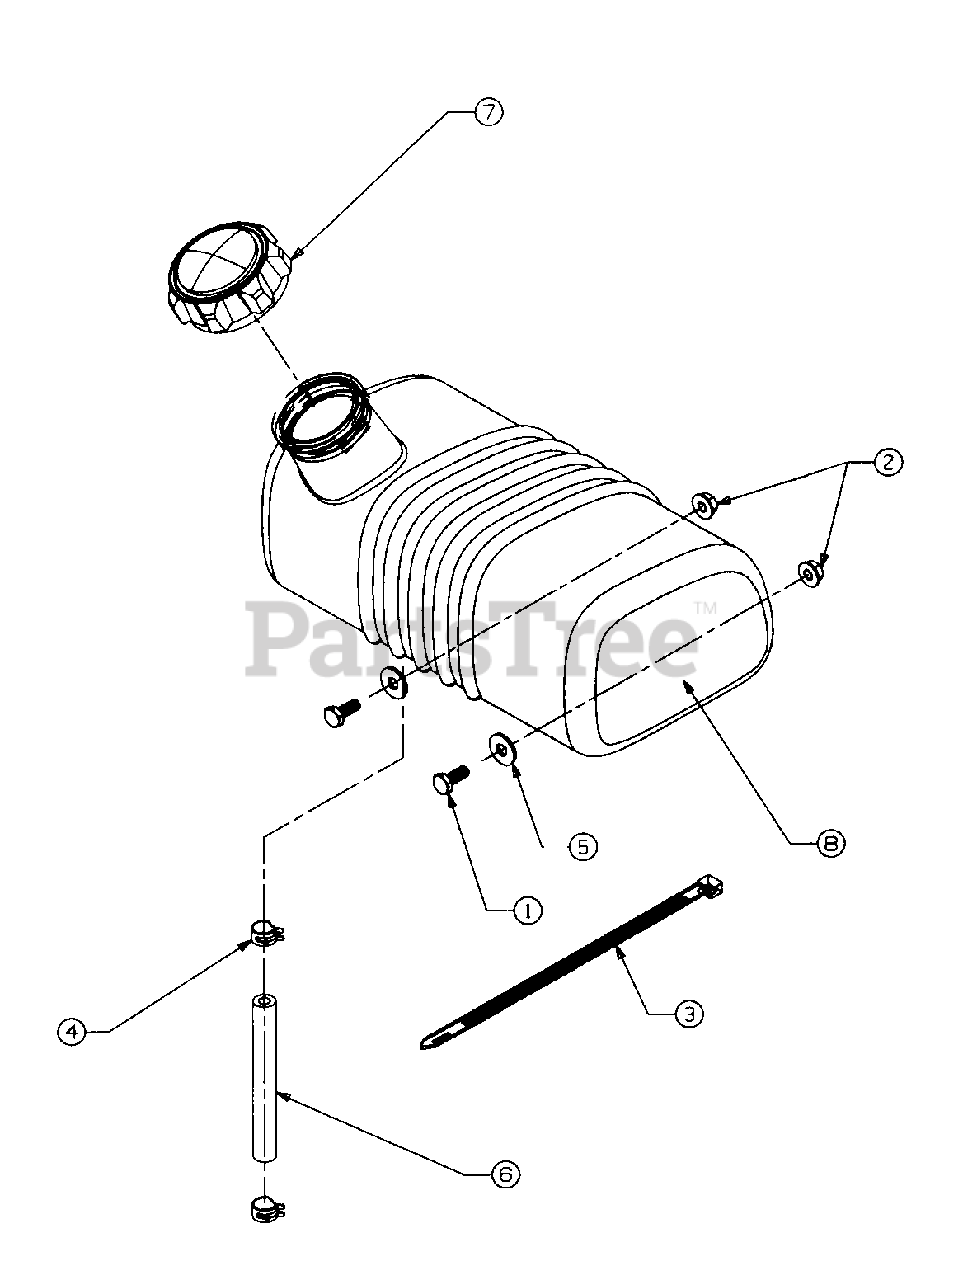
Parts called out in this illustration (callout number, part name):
1	SCREW-HEX
2	NUT-HEX LOCK FLANGE
3	CABLE TIE
4	CLAMP-HOSE
5	WASHER-FLAT
6	HOSE-FUEL LINE 12"
7	CAP-FUEL
8	TANK-FUEL 1 GALLON
